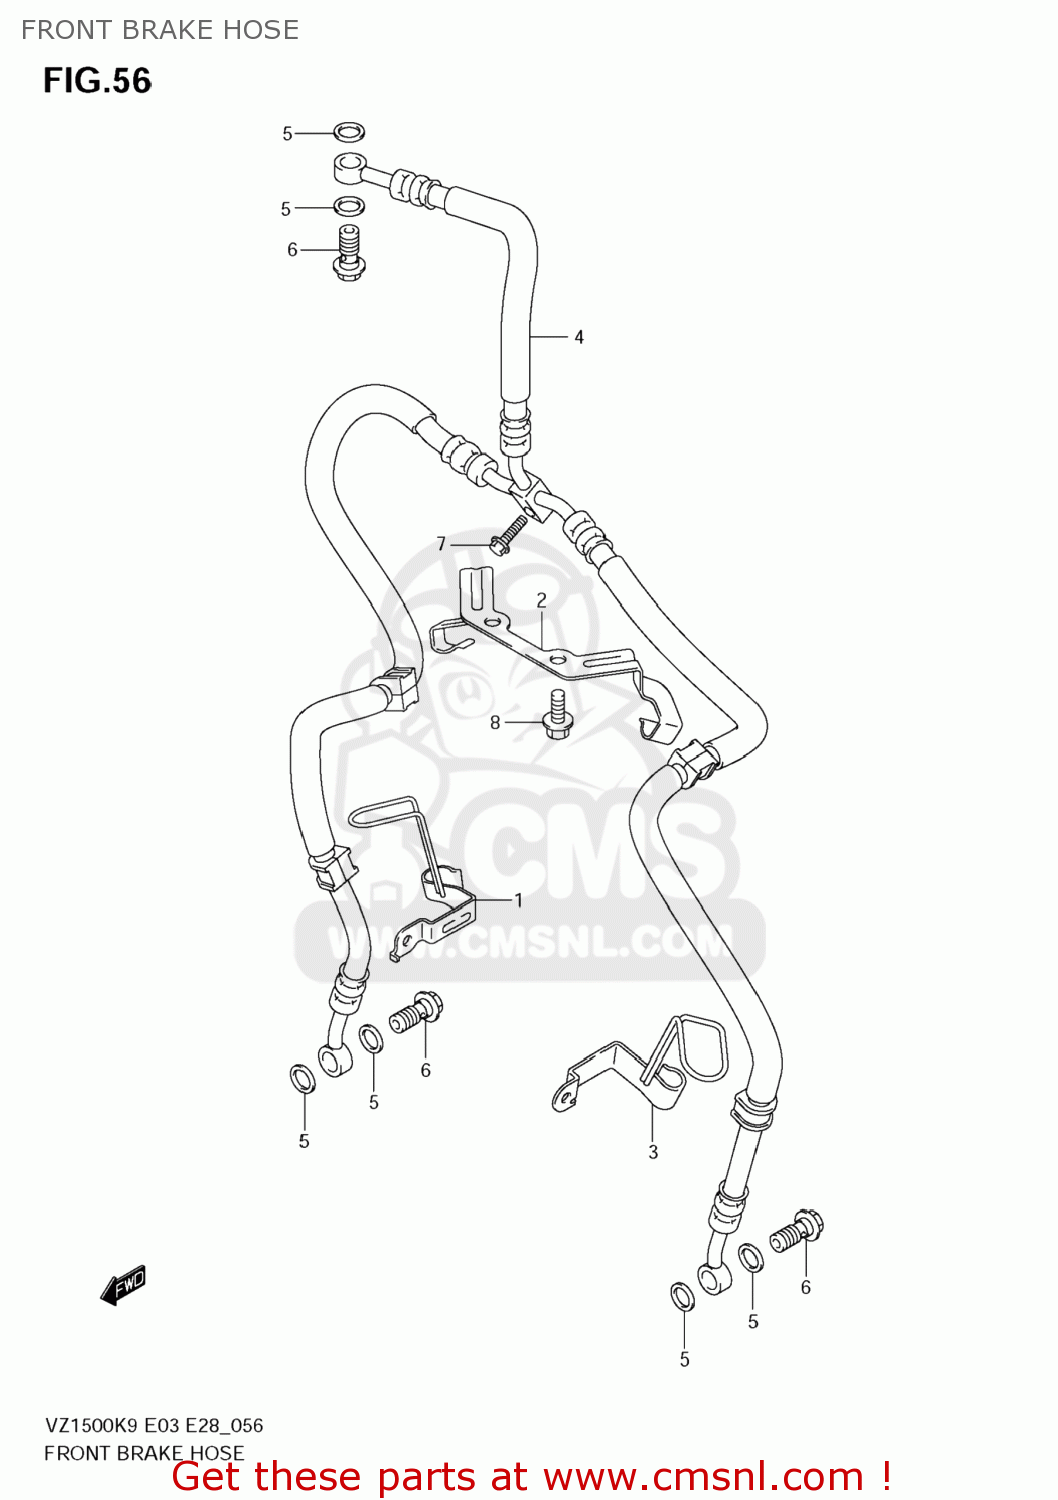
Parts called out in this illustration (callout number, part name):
1	CLAMP,FR BRAKE HOSE,R
2	CLAMP,FR BRAKE HOSE
3	CLAMP,FR BRAKE HOSE,L
4	HOSE,FR BRAKE
5	WASHER(10X15X1.5)
6	BOLT UNION
7	BOLT
8	BOLT
